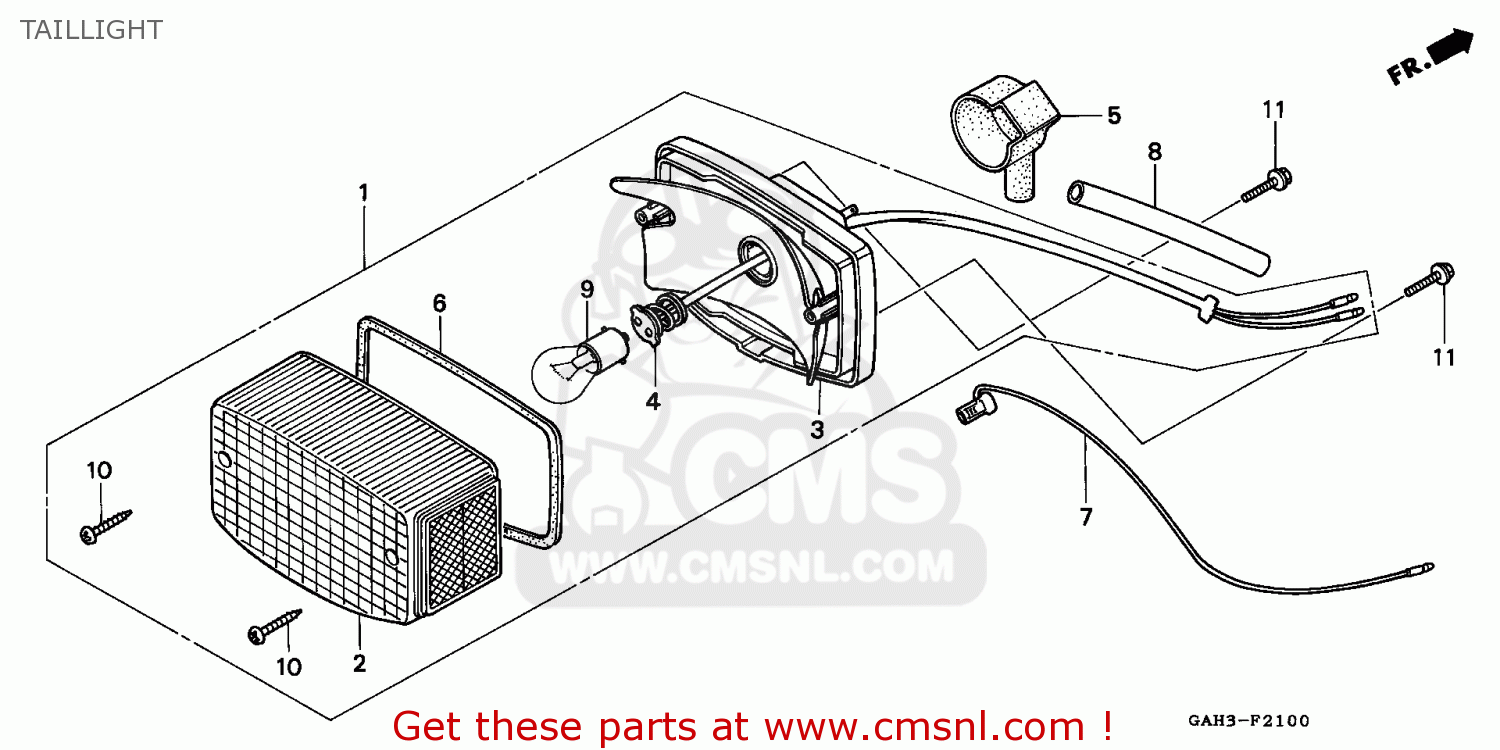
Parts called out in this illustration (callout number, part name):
1	UNIT TAIL LIGHT
2	LENS,TAIL LIGHT
3	SOCKET COMP.,TAIL
4	CORD COMP., TAILLIGHT
5	COVER, TAILLIGHT
6	PKG,TAILLIGHT LEN
7	CORD COMP., EARTH
8	TUBE, PROTECTOR
9	BULB,TAILLIGHT
10	SCREW,TAPP,4X40
11	SCREW,WASHER,5X16
